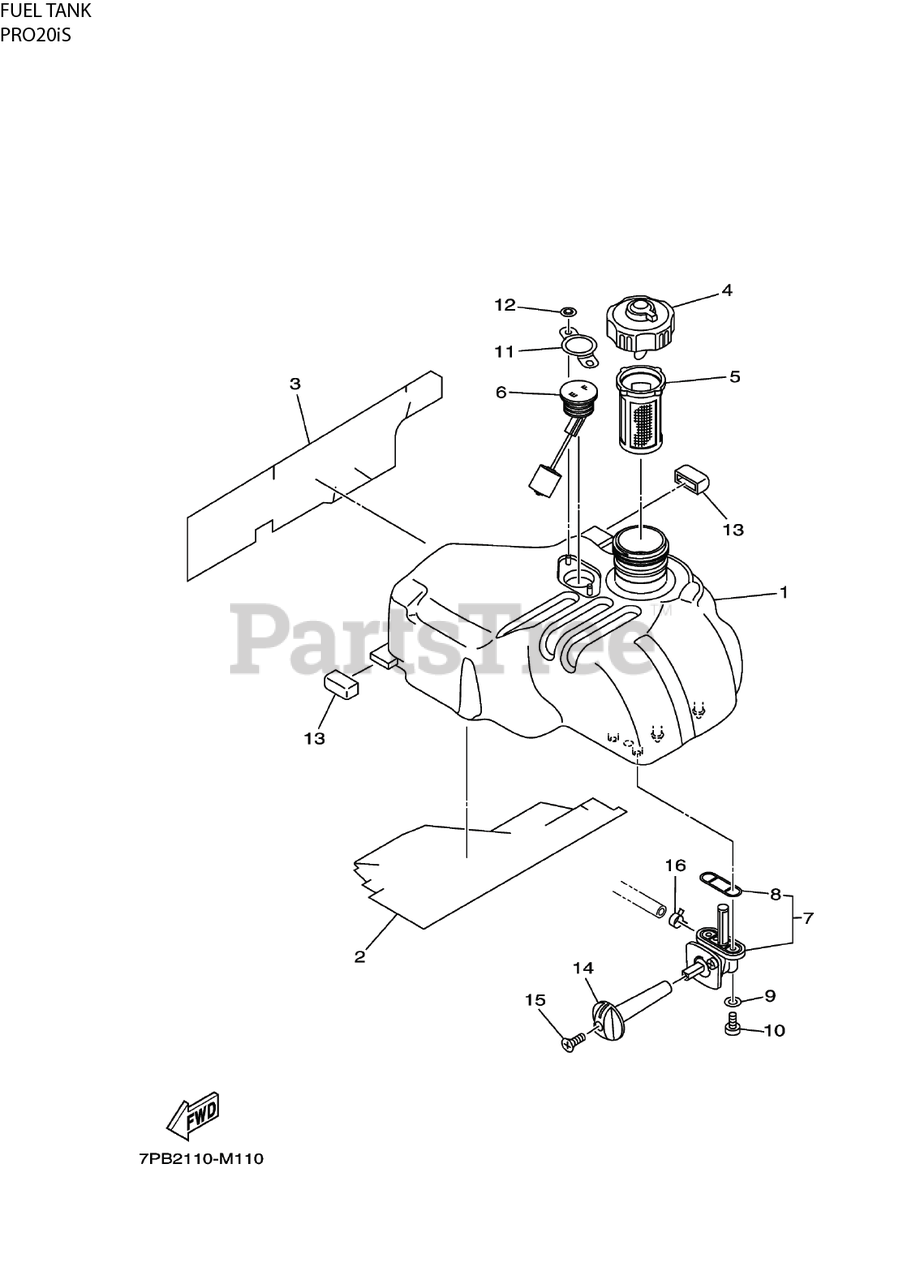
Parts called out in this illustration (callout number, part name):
1	BAFFLE - AIR SHROUD, CYLINDER
2	COVER, AIR CLEANER -PROTECTOR, FUEL TANK
3	COVER, AIR CLEANER - COVER SIDE 1
4	CAP ASSEMBLY
5	FILTER, STRAINER
6	FUEL LEVEL GAUGE ASSEMBLY
7	VALVE, FUEL COCK ASSEMBLY 1
8	O-RING, GASKET
9	WASHER, PLATE
12	NUT, SPRING
13	DAMPER, LOCATING 1
14	KNOB - LEVER, COCK
15	SCREW - FLAT HEAD
16	CLAMP - CLIP
